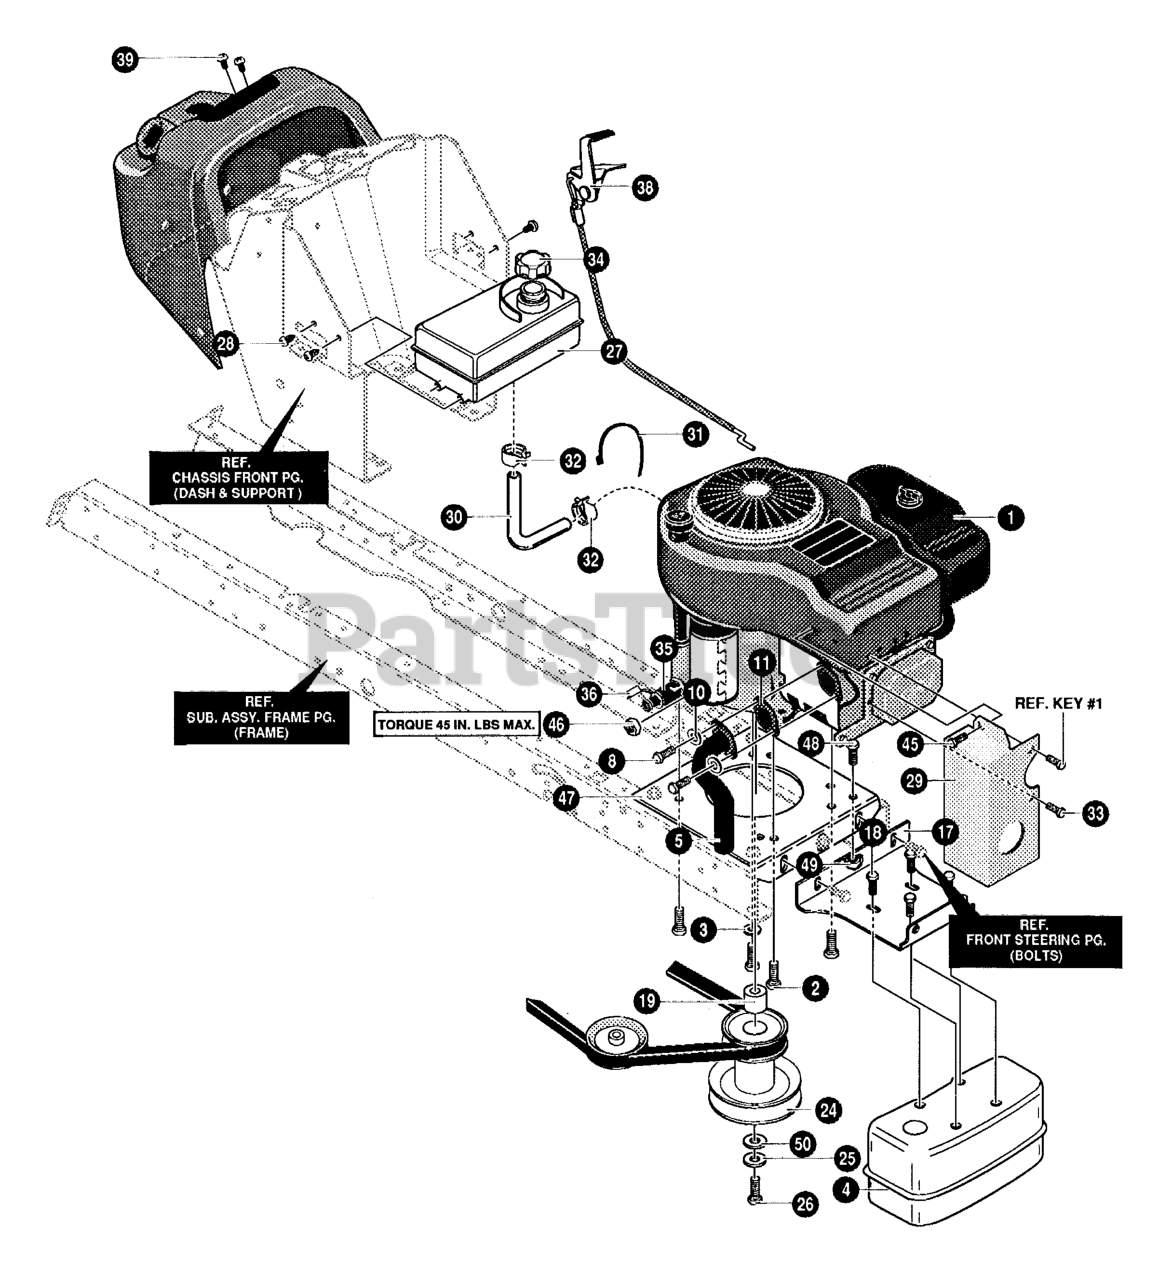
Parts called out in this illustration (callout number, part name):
1	ENGINE 15HP BS OHV IC
2	SCREW, 3/8- 16X1.25
4	MUFFLER, SINGLE- CYLINDER
5	EXHAUST TUBE
8	SCREW 5/16- 18X.75
10	WASHER
11	GASKET, MUFFLER
17	BRACKET, MUFFLER MOUNT
18	SCREW, 1/4-20X.75
19	SPACER, SLEEVE
24	PULLEY, STACK ASSY
27	TANK, FUEL 1.4 GAL.
29	HEAT SHIELD
30	TUBING
31	CABLE TIE
32	CLAMP, GAS
33	SCREW 1/4-20X/50
34	CAP, FUEL
35	OIL DRAIN
36	CAP, OIL DRAIN
38	THROTTLE CONTROL
39	SCREW, #8- 16X.50
45	SCREW 10- 16X.50
46	NUT 1/4-20
47	PLATE, ENGINE
48	SCREW, 5/16-18 x 0.75
49	NUT, 5/16- 18
50	FLATWASHER
